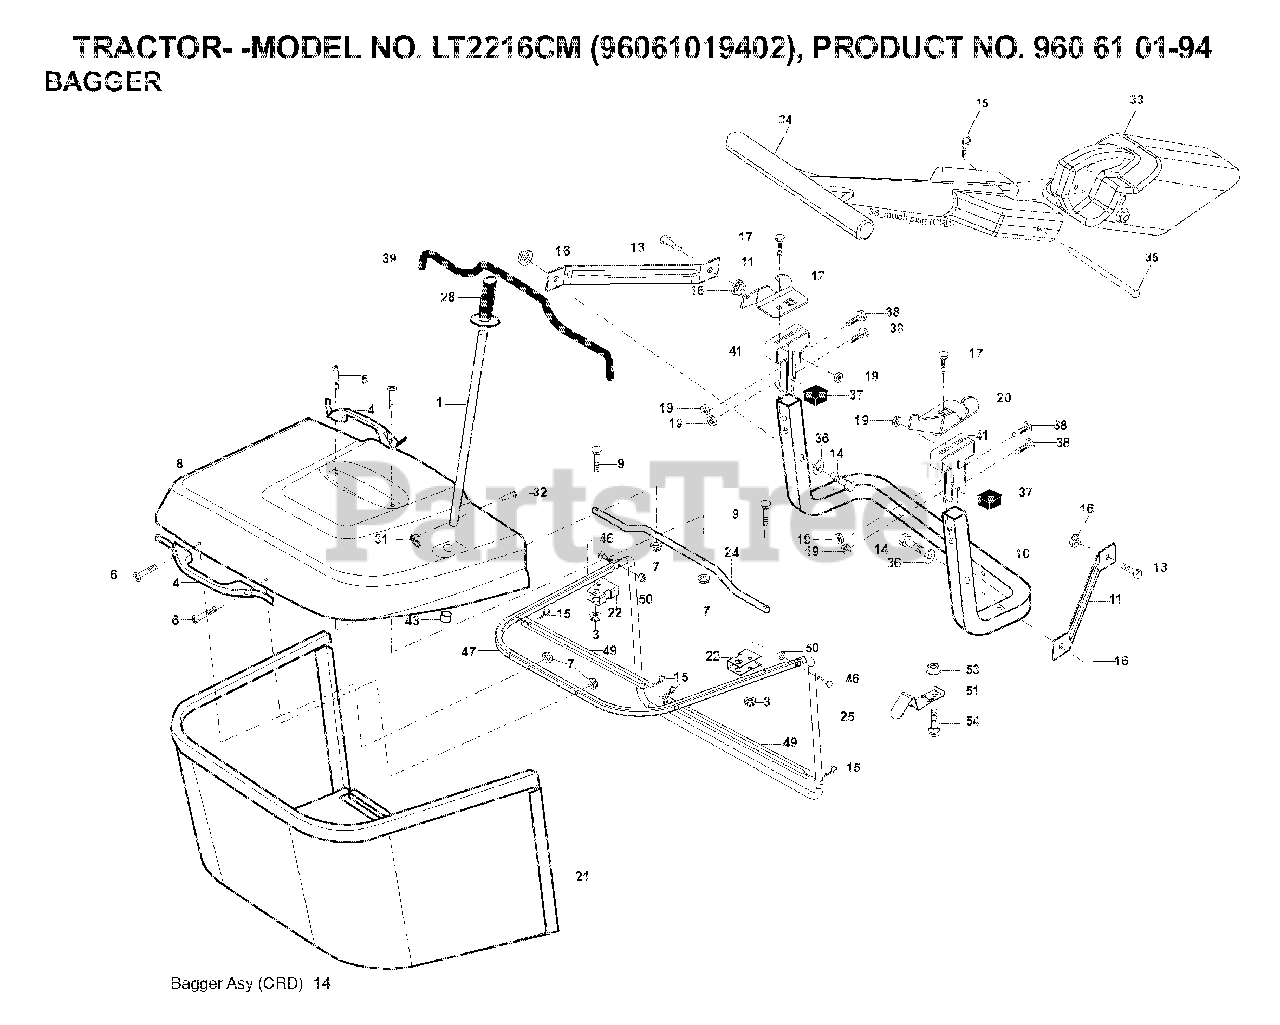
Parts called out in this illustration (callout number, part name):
1	TUBE HANDLE
3	NUT T
5	SCREW.PAN.HEAD
11	BRACKET
14	BOLT-HEX EAK
15	RETAINER-SPRNG RB
16	NUT LOCK FLG 3/8-16 UNC
17	BOLT
19	NUT LOCK HEX FLANGE 5/16-18
20	BRKT.PIVOT.RH.CRD
21	BAGGER.ASM.CRD.2007
22	BRACKET
24	TUBE
28	GRIP.HANDLE.BLACK
31	RETAINER CLIP
32	RIVET,DRILLED
33	PLUG
35	PIN
38	BOLT.5/16-18X2.5
41	BRKT, BAGGER
43	PLUG, TUBING END
46	BOLT.CARRIAGE.5/16-18
50	NUT.71038.31-18.HEX.NYLOCK
53	NUT
54	BOLT
